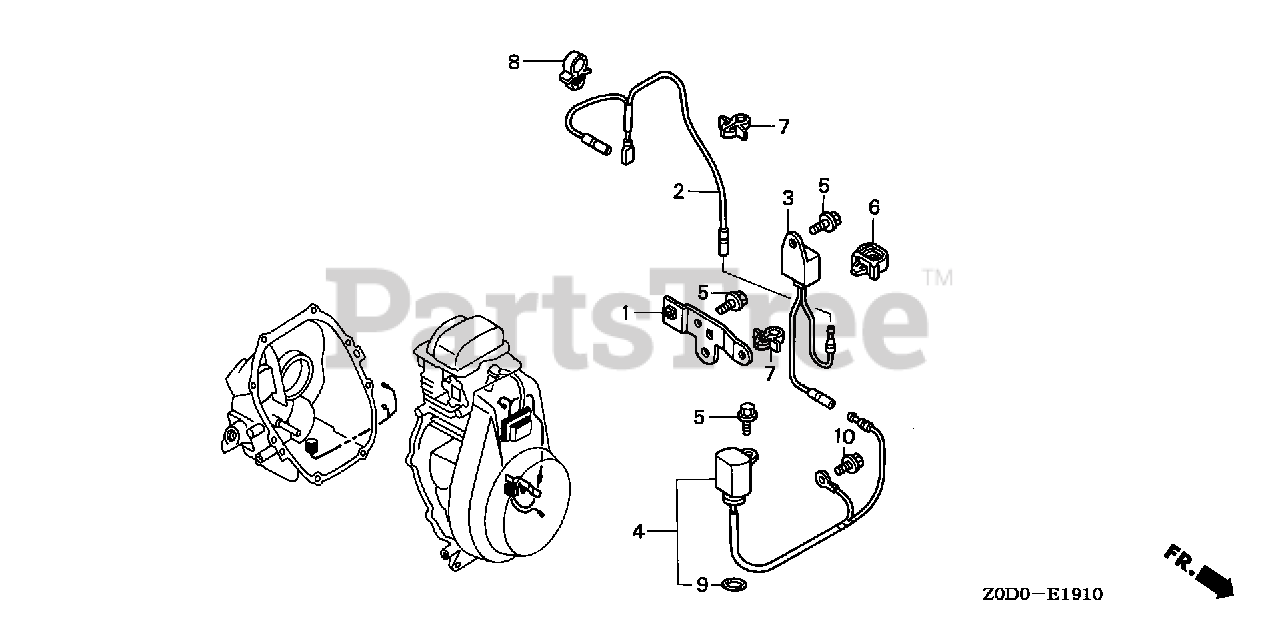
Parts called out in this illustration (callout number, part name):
1	BRACKET, OIL ALERT UNIT
2	WIRE, STOP SWITCH
3	ALERT UNIT, OIL
4	SWITCH ASSY., OIL LEVEL
5	BOLT, FLANGE (6X14) (CT200)
6	CLIP, WIRE HARNESS (10MM)
7	CLIP A, CABLE (3.8MM BLACK) (NIFCO)
8	CLIP B, CABLE (9MM BLACK)
9	O-RING (11.8X2.4)
10	BOLT, FLANGE (6X8)
